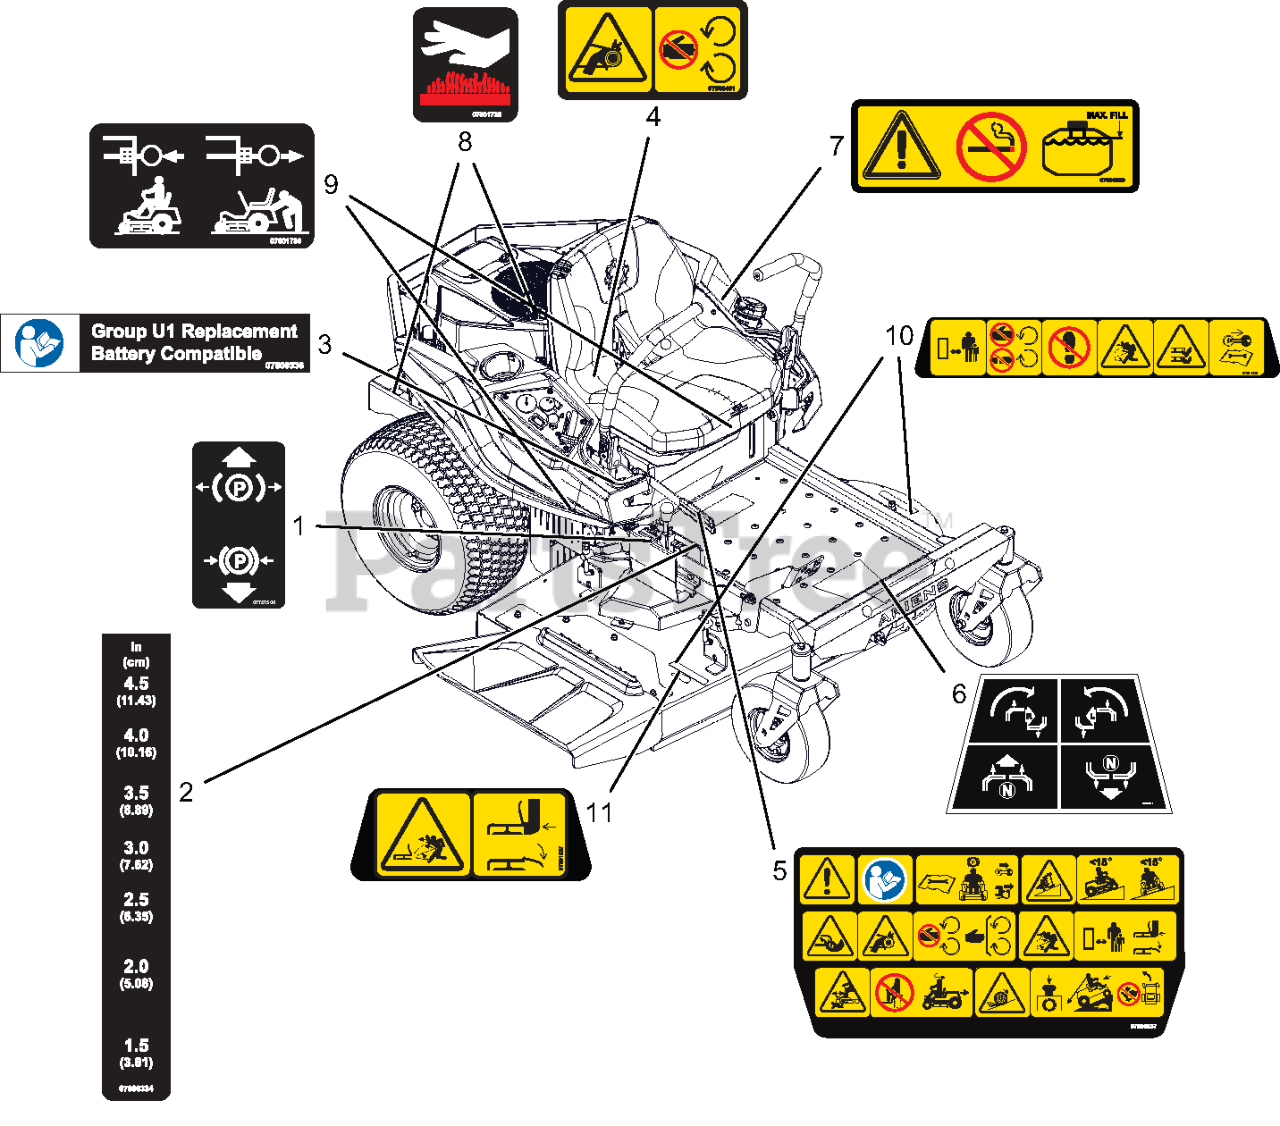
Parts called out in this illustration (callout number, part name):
1	DECAL, PARKING BRAKE LEVER
2	DECAL, HEIGHT OF CUT
3	DECAL, U1 BATTERY REPLACEMENT
4	DECAL, SAFETY - GUARDING
5	DECAL, MAIN SAFETY
6	DECAL, STEERING
7	DECAL, FUEL WARNING
8	DECAL- HOT SURFACE
9	DECAL- TRANSAXLE DISCONNECT
10	DECAL- SAFETY - MOWER DECK
11	DECAL- SAFETY - DECK GUARDING
